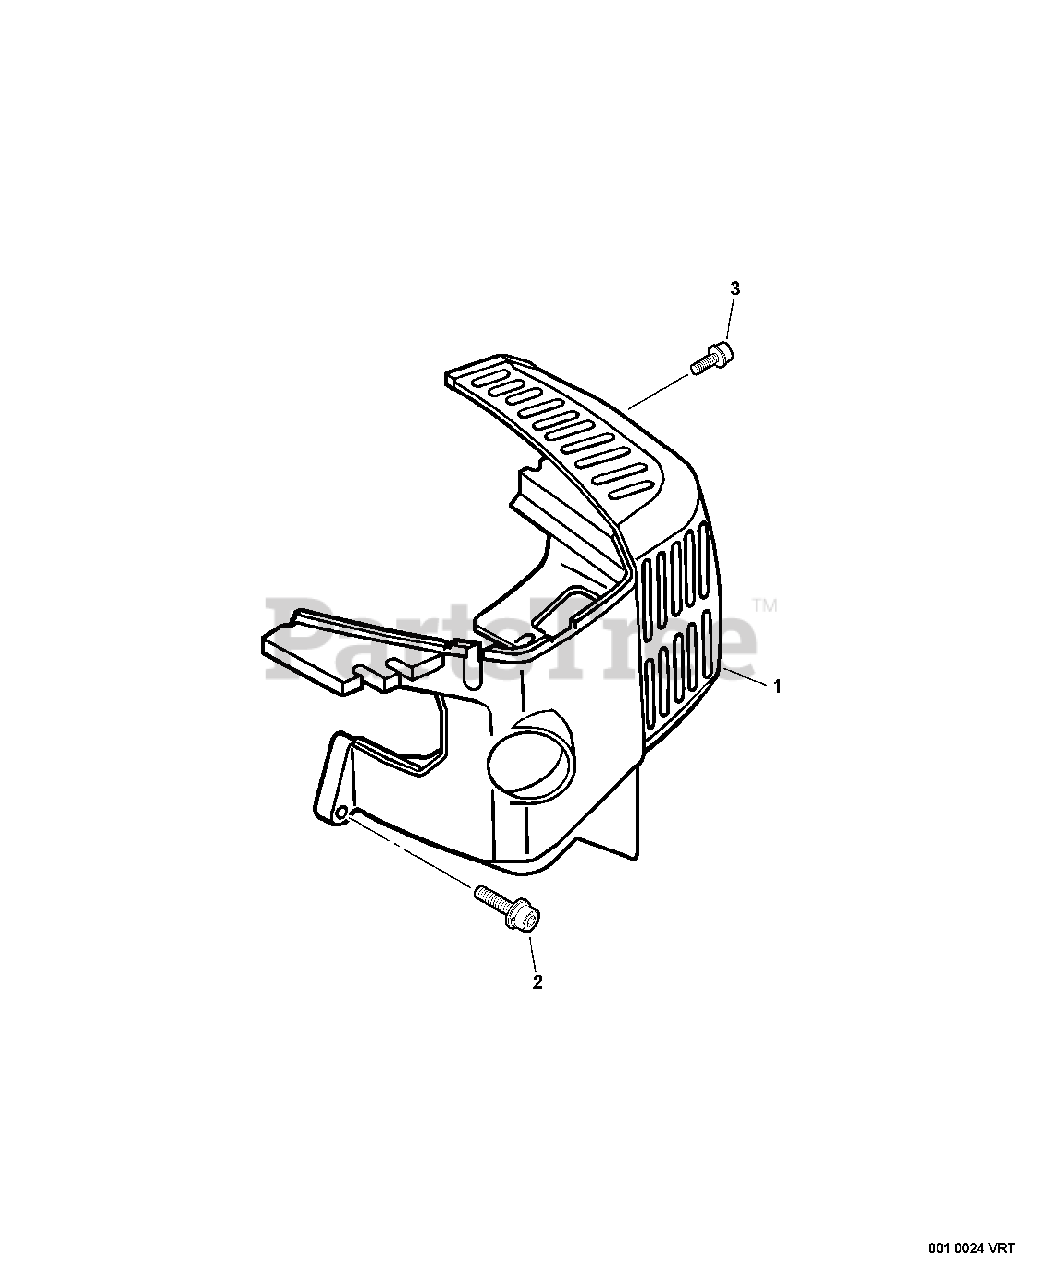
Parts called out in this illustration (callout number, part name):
1	COVER, ENGINE
2	SCREW 4×22
3	BOLT 4×8
